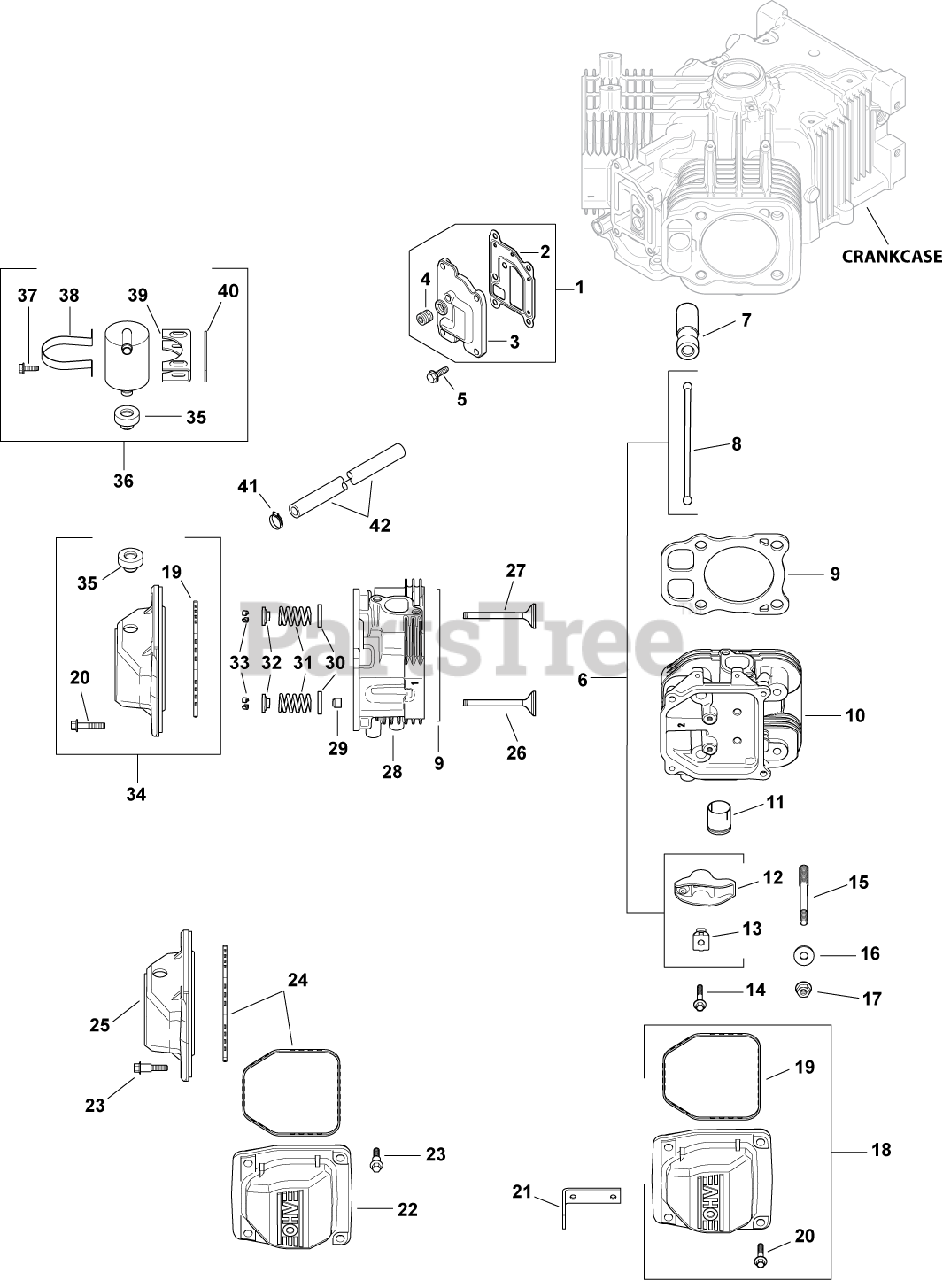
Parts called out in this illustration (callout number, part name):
1	KIT, BREATHER COVER W/GASKET
2	GASKET, BREATHER-USE 24 041 67-S
3	COVER, BREATHER -USE 24 096 125-S
4	PLUG, CTSK PIPE 1/8"
5	SCREW,FLG THD FRM M6X1.0X20-(#25086396S)
6	KIT, VALVE TRAIN
7	LIFTER, HYDRAULIC VALVE-USE 25 351 10-S
8	ROD, PUSH
9	CYL HEAD GASKET KIT-USE 24 841 04-S
10	HEAD, ASSEM CYLINDER #2 -USE 24 318 116-
11	LINER, EXHAUST PORT-USE 24 605 07-S
12	ARM, ROCKER
13	PIVOT, ROCKER ARM
14	SCREW, FLG M6X1.0X34
15	STUD, M8X1.25
16	WASHER, FLAT 8.6 MM
17	NUT, FLG M8X1.25
18	KIT, VALVE COVER-PLAIN
19	O-RING (YELLOW) -USE 24 153 30-S
20	SCREW, FLG M6X1.0X30
21	STRAP, LIFTING-USE 25 445 03-S
23	SCREW, SHOULDER
24	O-RING (BLACK)
26	VALVE, EXHAUST (STD) - USE 32 016 01-S
27	VALVE, INTAKE (STD)
28	HEAD, ASSEM CYLINDER #1 -USE 24 318 108-
29	SEAL, VALVE STEM - (#2503214S)
30	RETAINER, SPRING
31	SPRING, VALVE
32	RETAINER, VALVE SPRING - USE 25 173 28-S
33	KIT, RETAINER
34	KIT, VALVE COVER
35	GROMMET, RUBBER
36	KIT, BREATHR SEPARATR-(#24755241S)
37	SCREW,FLG THD FRM M5X0.8X16-(#25086398S)
38	STRAP, BREATHER - USE 24 755 241-S
39	BRACKET, BREATHER SEPARATOR
40	SPACER
41	CLAMP, HOSE (KM)-USE 25 237 31-S
42	HOSE, BREATHER-USE 24 326 63-S
2401602-S	VALVE, EXHAUST (.25)
2401702-S	VALVE, INTAKE (.25)
24318108-S	KIT, CYLINDER HEAD #1
24318116-S	KIT, CYLINDER HEAD #2
